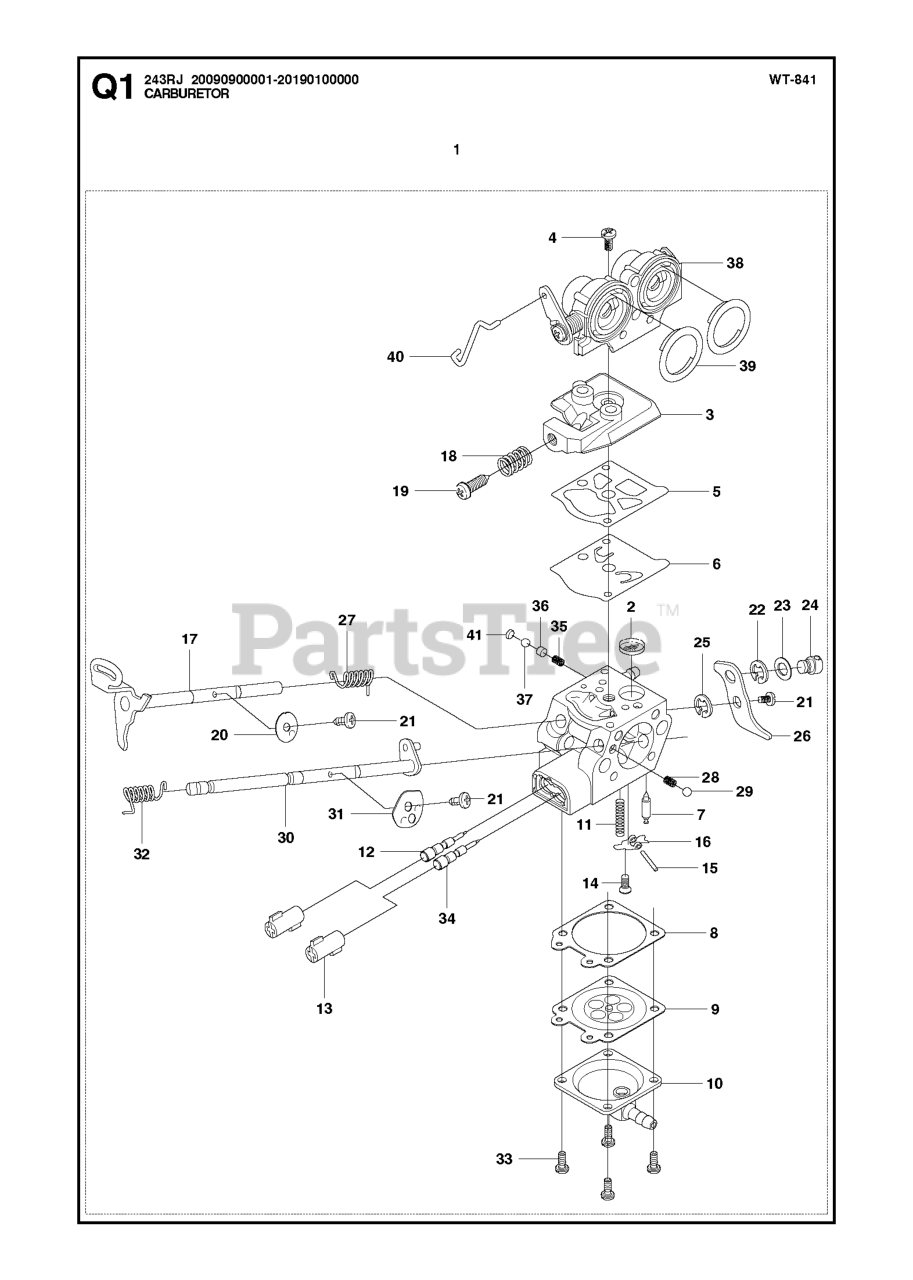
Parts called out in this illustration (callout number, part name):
2	SCREEN
7	VALVE INLET
26	LEVER, THROTTLE
27	SPRING RETURN
30	SHAFT, CHOKE
33	SCREW ASSY
36	PISTON
37	BALL
